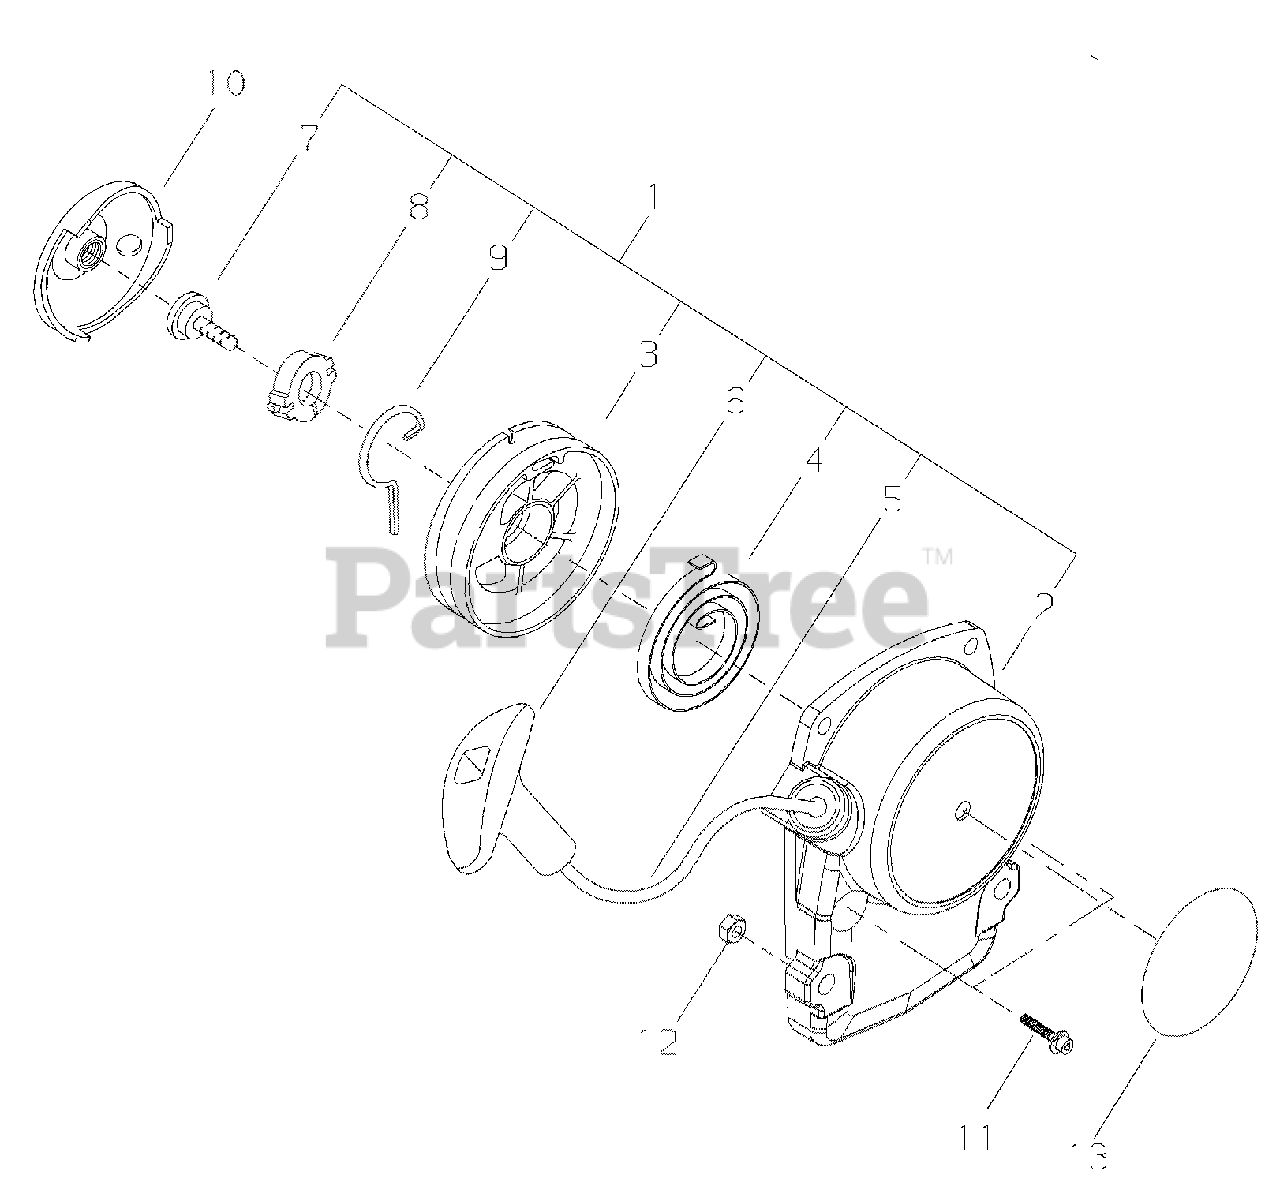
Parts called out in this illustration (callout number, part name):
1	STARTER ASSY
2	CASE, STARTER
3	REEL, ROPE
4	SPRING, REWIND
5	ROPE, STARTER
6	GRIP, STARTER
7	SCREW - 5
8	WASHER - 5
9	PAWL, STARTER
10	STARTER PAWL ASSY
11	SCREW - 4X16
13	LABEL - C242 PROFESSIONAL
